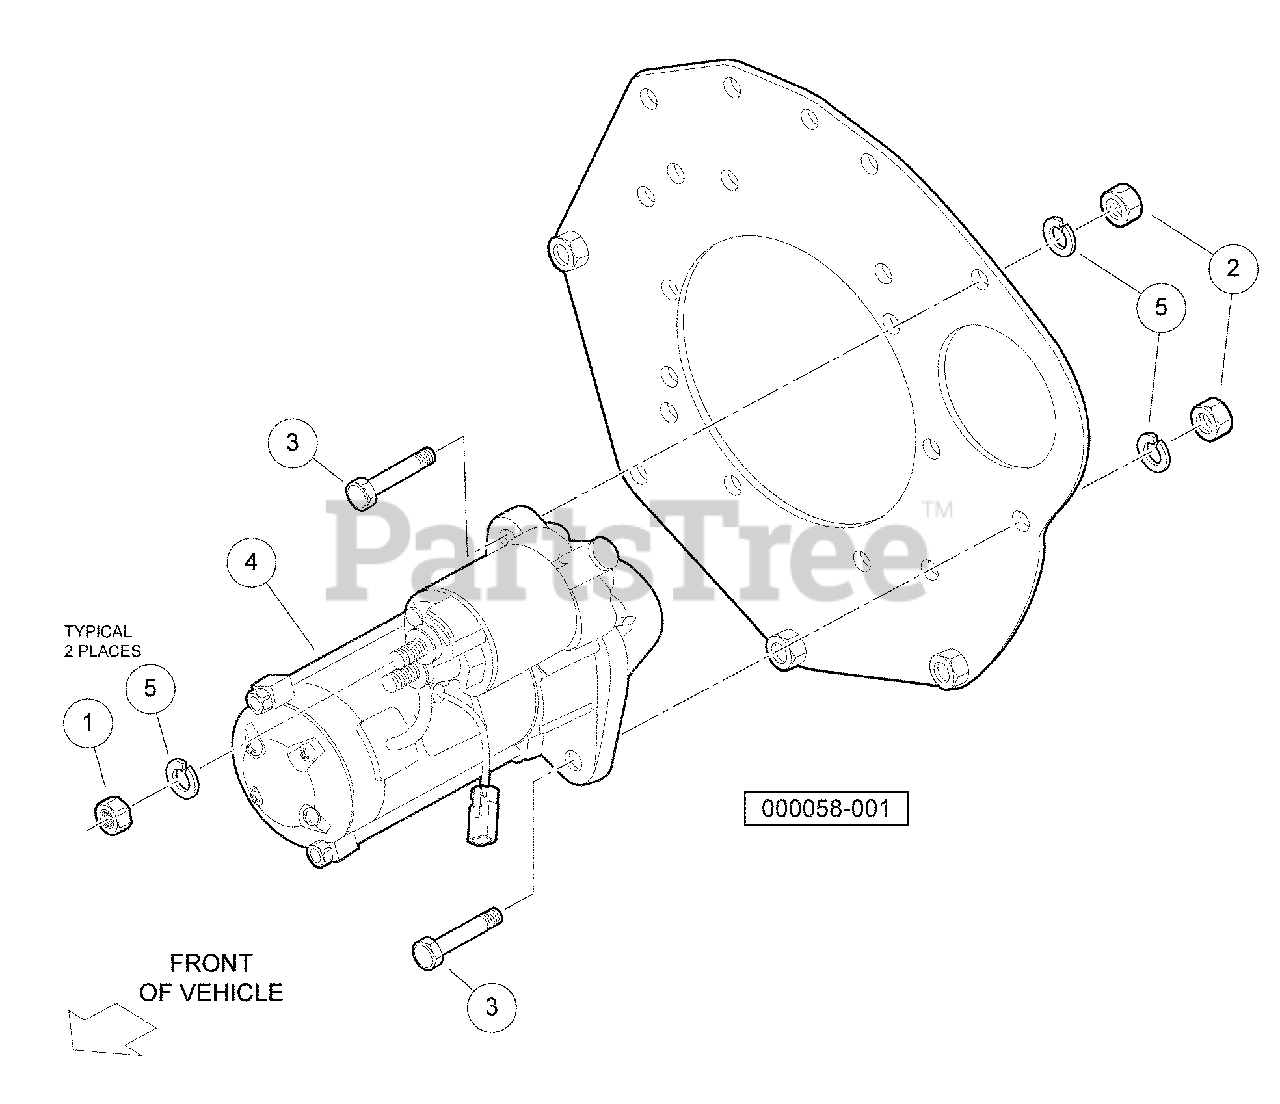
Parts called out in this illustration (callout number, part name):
1	Nut, D722, Starter
2	Nut, M8, Plate
3	Bolt, M8 X 1.25 X 28
4	Motor, Starter
5	Washer, Spring, D722, Starter
